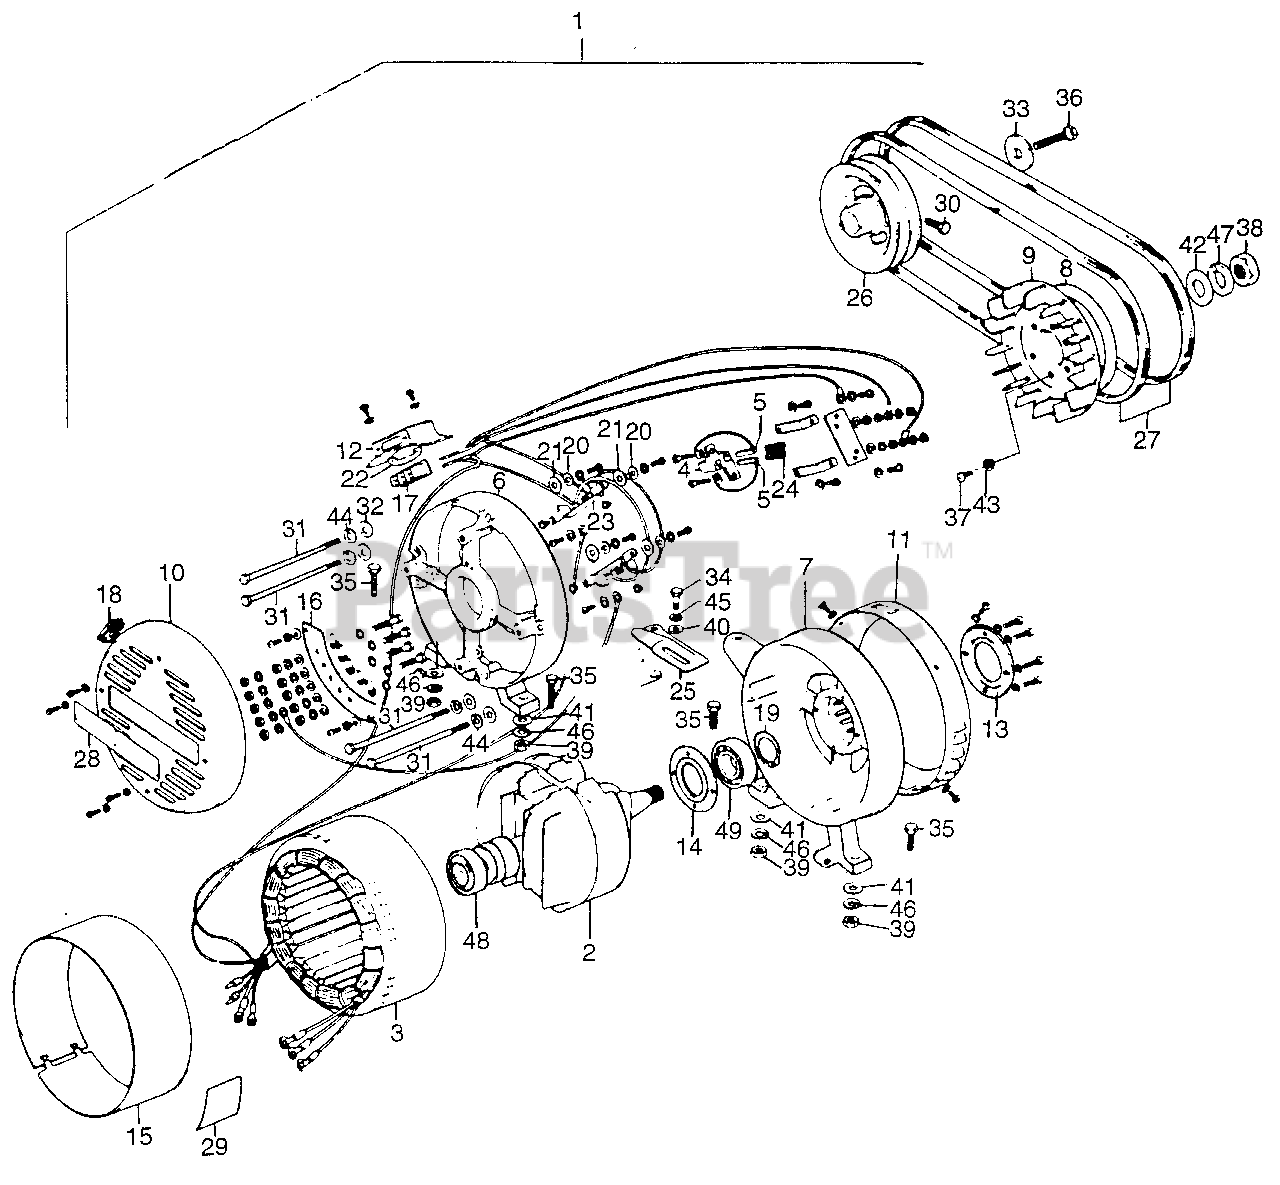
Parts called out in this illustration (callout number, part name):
1	ALTERNATOR ASSY.
2	ROTOR ASSY.
3	STATOR ASSY. (NOT AVAILABLE)
4	HOLDER, BRUSH
5	BRUSH, CARBON
6	COVER, END
7	COVER, FR.
8	PULLEY (NOT AVAILABLE)
10	COVER, GENERATOR *R8* (BRIGHT RED)
11	COVER, FAN *NH31* (MCKINLEY WHITE)
12	COVER, CONNECTOR
13	COVER A, BEARING (NOT AVAILABLE)
14	COVER B, BEARING (NOT AVAILABLE)
15	COVER, STATOR *NH31* (MCKINLEY WHITE) (NOT AVAILABLE)
16	TERMINAL ASSY.
17	CONNECTOR (6P)
18	BUSH, RUBBER
19	CIRCLIP (INNER)
20	BUSH, INSULATING
21	WASHER, INSULATING
22	PLATE, COVER
23	DIODE, D.C.
24	SPRING, BRUSH HOLDER (NA USE ALT:31106-815-169)
25	STAY, ALTERNATOR (NOT AVAILABLE)
26	V-PULLEY (60HZ) (NOT AVAILABLE)
27	V-BELT (A-31) (NOT AVAILABLE)
28	PLATE, CAUTION
29	PLATE SPEC
30	BOLT B, KEY LOCK (7MM) (NOT AVAILABLE)
31	BOLT, HEX. (6X145)
32	WASHER, FLAT (6MM) (NOT AVAILABLE)
33	WASHER, LOCK (8MM)
34	BOLT, HEX. (8X10)
35	BOLT, HEX. (10X32) (SOURCE: VINTAGE PARTS INC.)
36	BOLT, HEX. (8X25) (NOT AVAILABLE)
37	SCREW, PAN (5X10)
38	NUT, HEX. (18MM)
38	NUT, HEX. (18MM) (NOT AVAILABLE)
39	NUT, HEX. (10MM)
40	WASHER, PLAIN (8MM)
41	WASHER, PLAIN (10MM)
42	WASHER, FLAT (18MM)
43	WASHER, SPRING (5MM)
44	WASHER, SPRING (6MM)
45	WASHER, SPRING (8MM)
46	WASHER, SPRING (8MM)
47	WASHER, SPRING (18MM) (SOURCE: VINTAGE PARTS INC.)
48	BEARING, RADIAL BALL (6203UU)
49	BEARING, RADIAL BALL (6205UU)
